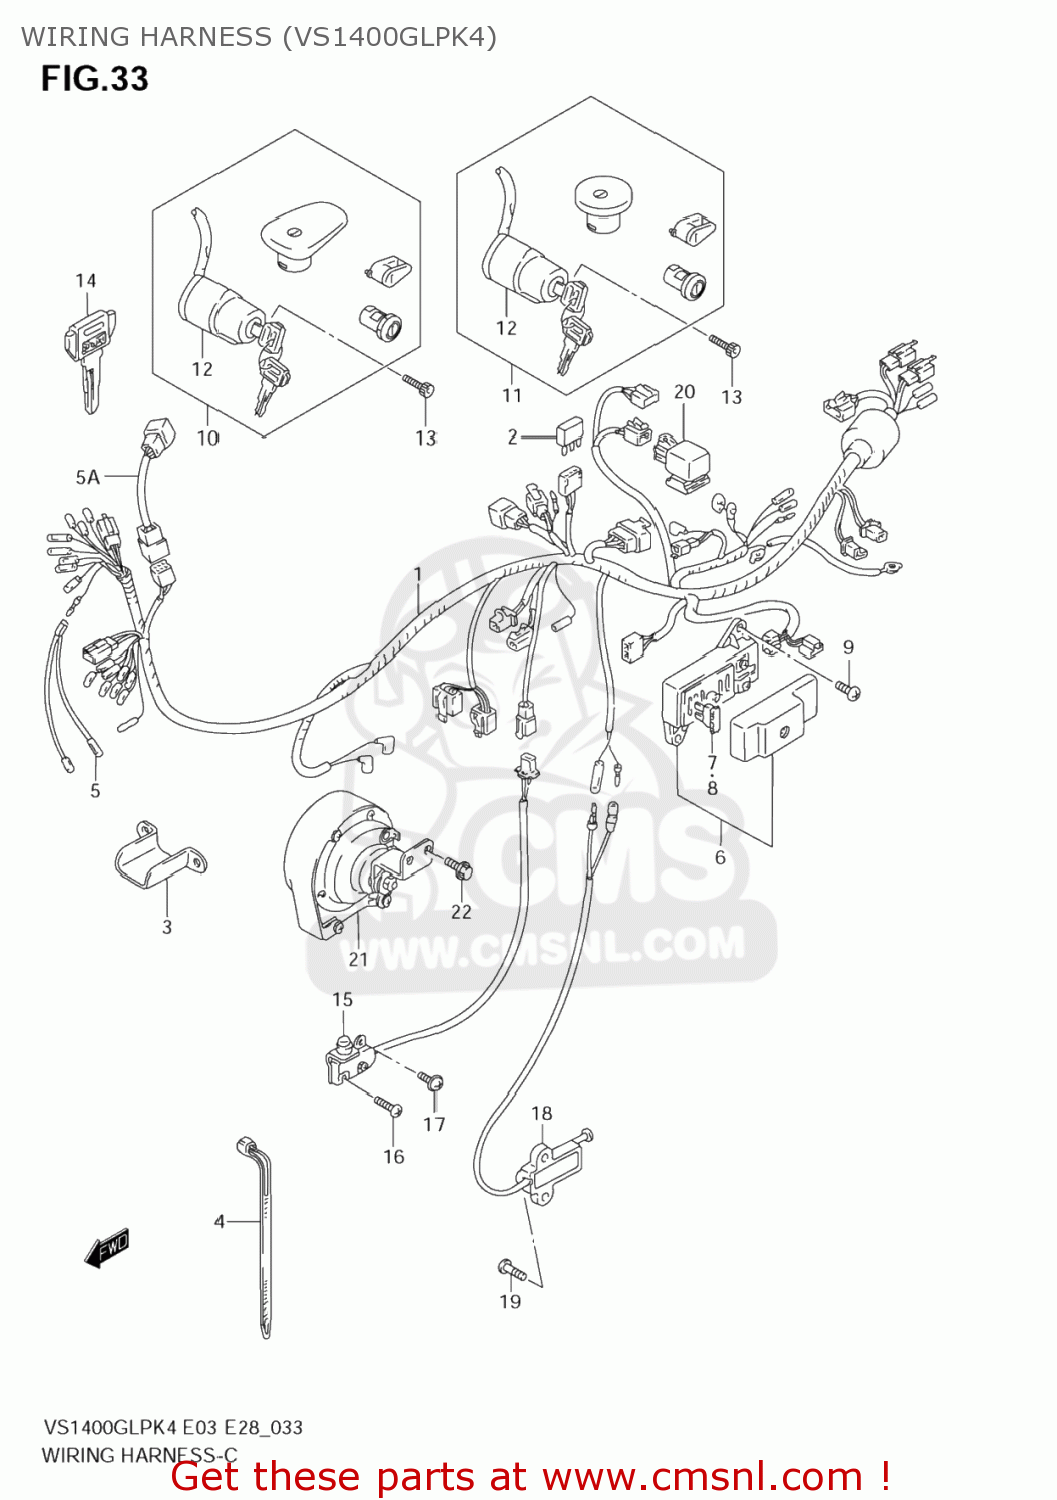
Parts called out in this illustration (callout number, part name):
1	HARNESS, WIRING
2	DIODE(STANLEY DE8804)
3	GUIDE,WIRING HARNESS
4	CLAMP(L:125)
5	WIRE,CLUTCH SW CONNECTOR
5A	WIRE,IGNITION LEAD
6	BOX ASSY,FUSE
7	FUSE (25A)
8	FUSE(10A)
9	SCREW
10	LOCK SET
11	LOCK SET
12	SWITCH ASSY,IGNITION
13	BOLT
14	KEY,BLANK(TYPE:C)
15	SWITCH ASSY,STOP LAMP
16	SCREW 4X16
17	SCREW
18	SWITCH ASSY,SIDE STAND
19	SCREW
20	RELAY ASSY
21	HORN ASSY
22	BOLT
